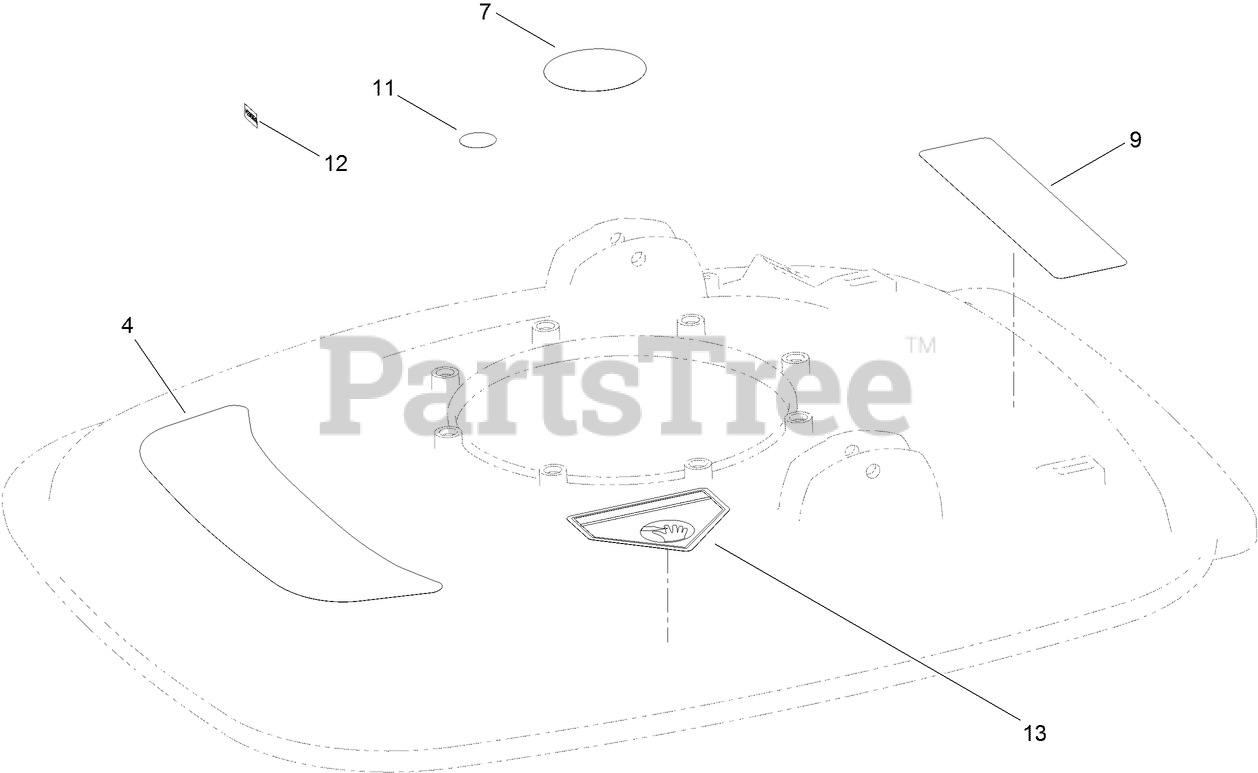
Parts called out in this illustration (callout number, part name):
4	DECAL-HOVER PRO
7	DECAL-ENGINE
9	DECAL-WARNING
11	DECAL
12	DECAL-STOP
13	DECAL-DANGER
